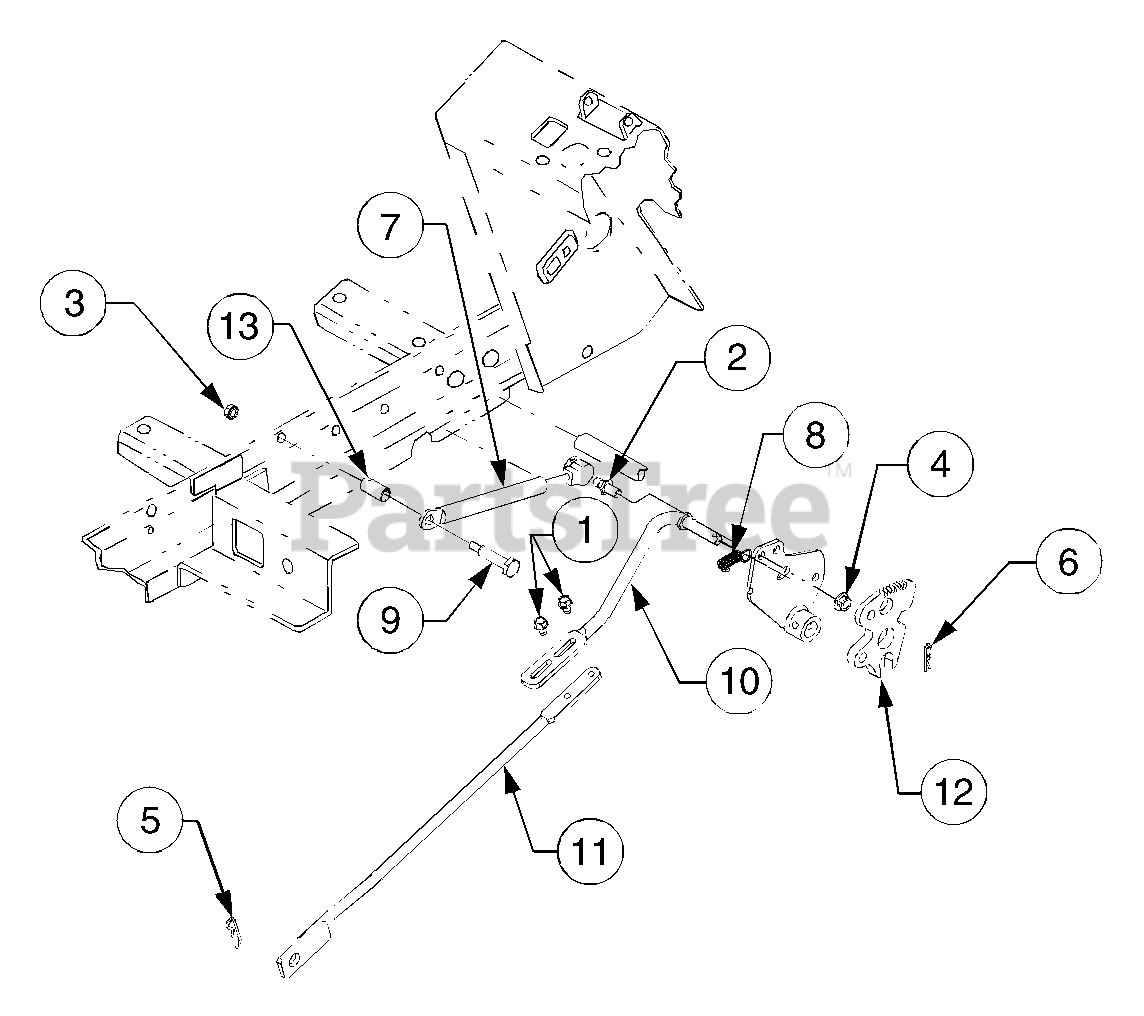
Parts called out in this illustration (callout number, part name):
1	Screw, Hex Wsh Hd Tapp, 1/4-20 x .75
2	Screw, Ball, 5/16-18 x.56
3	Nut, Hex Sems, 1/4-20
4	Nut, Hex Flange Lock, 1/4-20
5	Pin, Internal Cotter
6	Pin, Internal Cotter
7	Cylinder, Damper
8	Spring, Extension, 3/8 OD x 1.44
9	Bolt, Shoulder, .374 Dia x 1.375
10	Rod, Front Control
11	Rod, Rear Hydro Control
12	Plate, Cruise
13	Spacer, Split Tubing, .375 ID x 1.04
